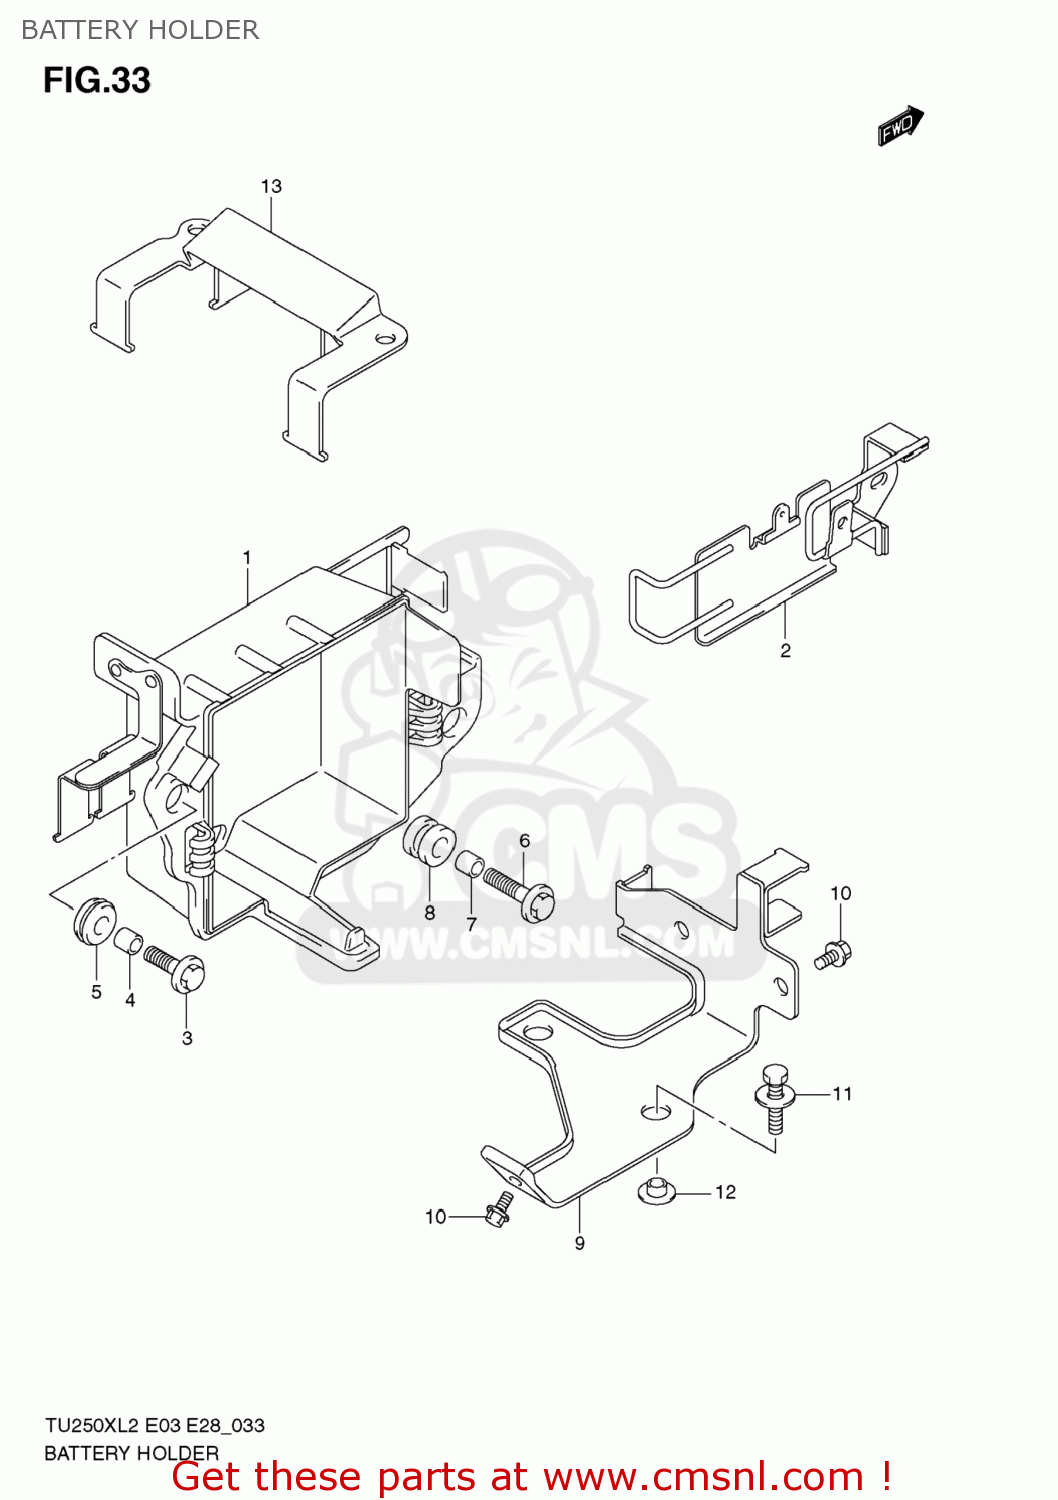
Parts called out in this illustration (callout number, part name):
1	HOLDER,BATTERY
2	BAND,BATTERY HOLDER
3	BOLT(6X25)
4	SPACER(6.5X9X9)
5	CUSHION
6	BOLT(6X25)
7	SPACER(6.5X9X9)
8	CUSHION
9	PLATE,ELECTRIC PARTS NO.1
10	SCREW
11	SCREW
12	SPACER(6.5X10X2.5)
13	PLATE,ELECTRIC PARTS NO.2
